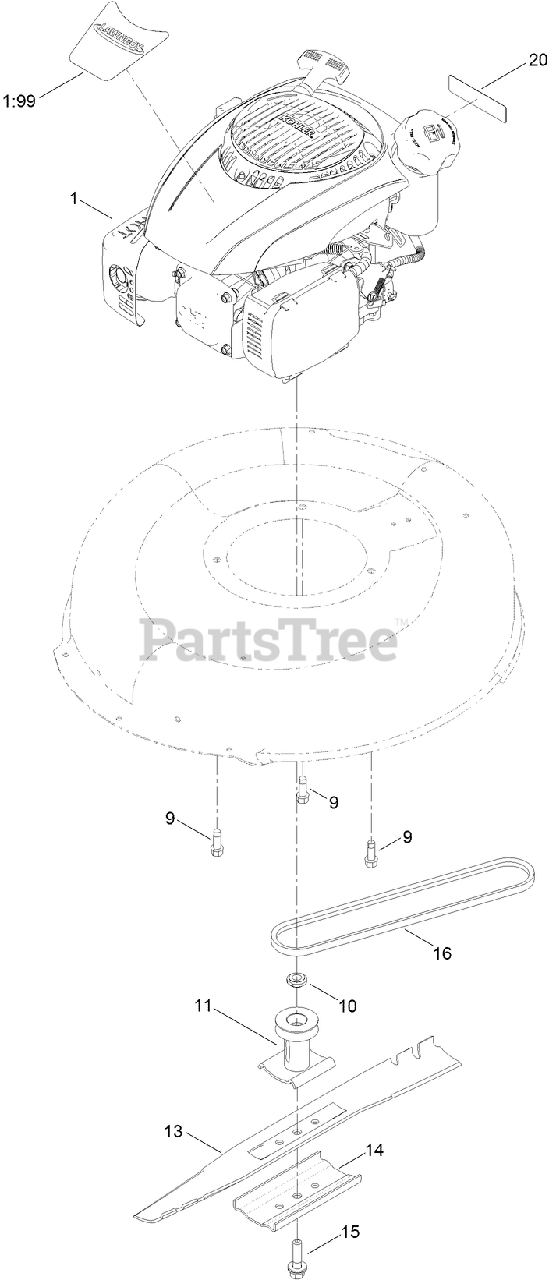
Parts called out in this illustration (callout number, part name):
1:99	DECAL-SHROUD
9	SCREW-TAPTITE
10	SPACER-DRIVER
11	DRIVER-BLADE
14	SUPPORT-BLADE
15	BOLT-BLADE
20	DECAL-ARRESTER, SPARK
